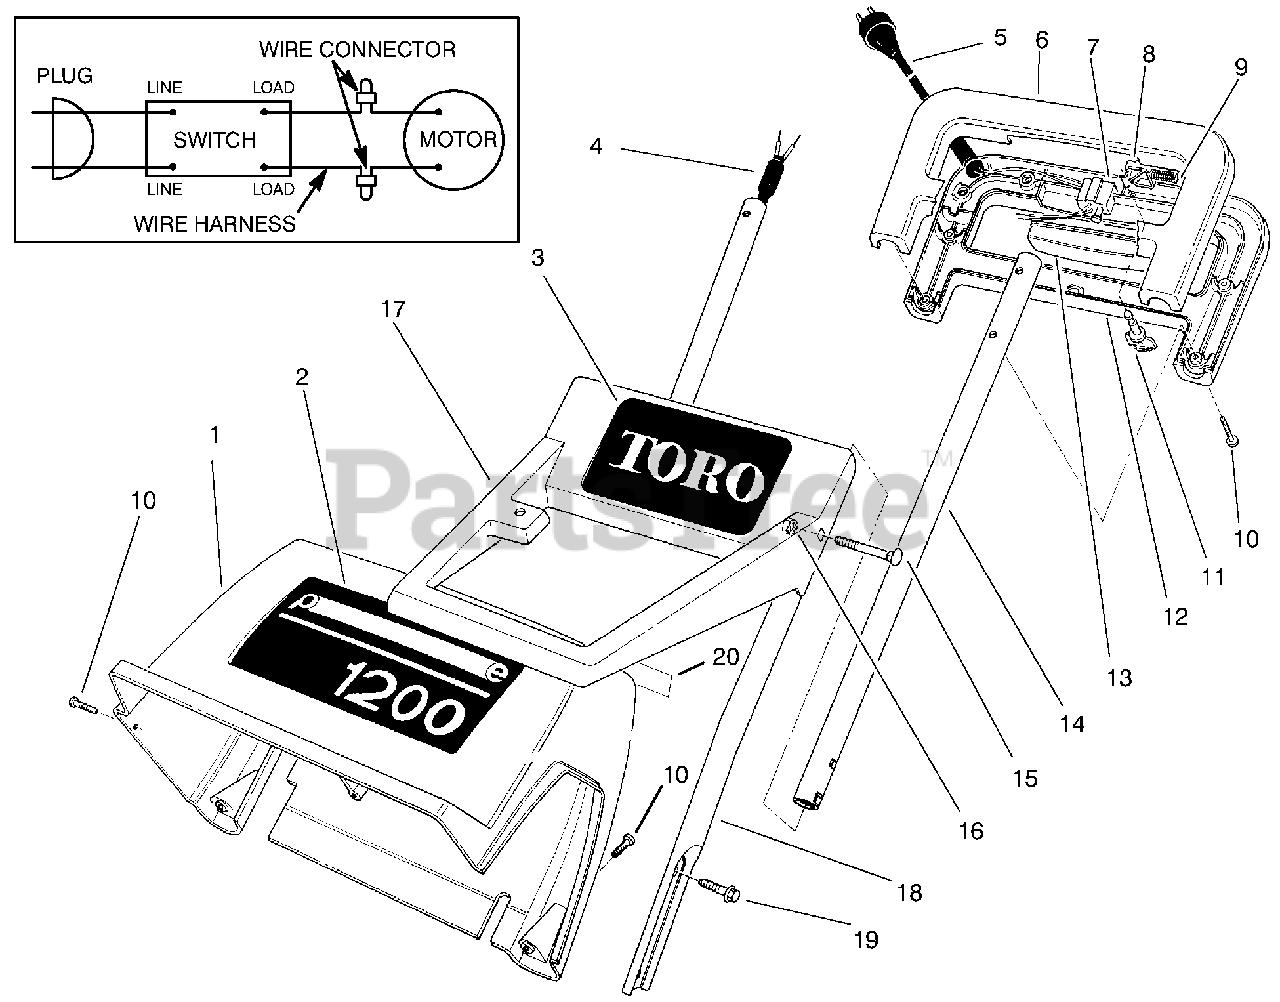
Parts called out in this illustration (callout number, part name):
2	Decal-1200
3	Decal-Toro
4	Wire Harness
5	Cord Supply
6	Handle-Upper Control
7	Switch-Starter
8	Switch-Lockout
9	Spring-Compression
10	Screw-Self Tap. Pan Hd.
12	Handle-Lower Control
13	Bar-Switch
14	Tube-Upper
15	Bolt-Carriage
16	Nut-Lock
17	Handle-Middle
18	Handle-Lower L.H.
20	Decal-U.L.
